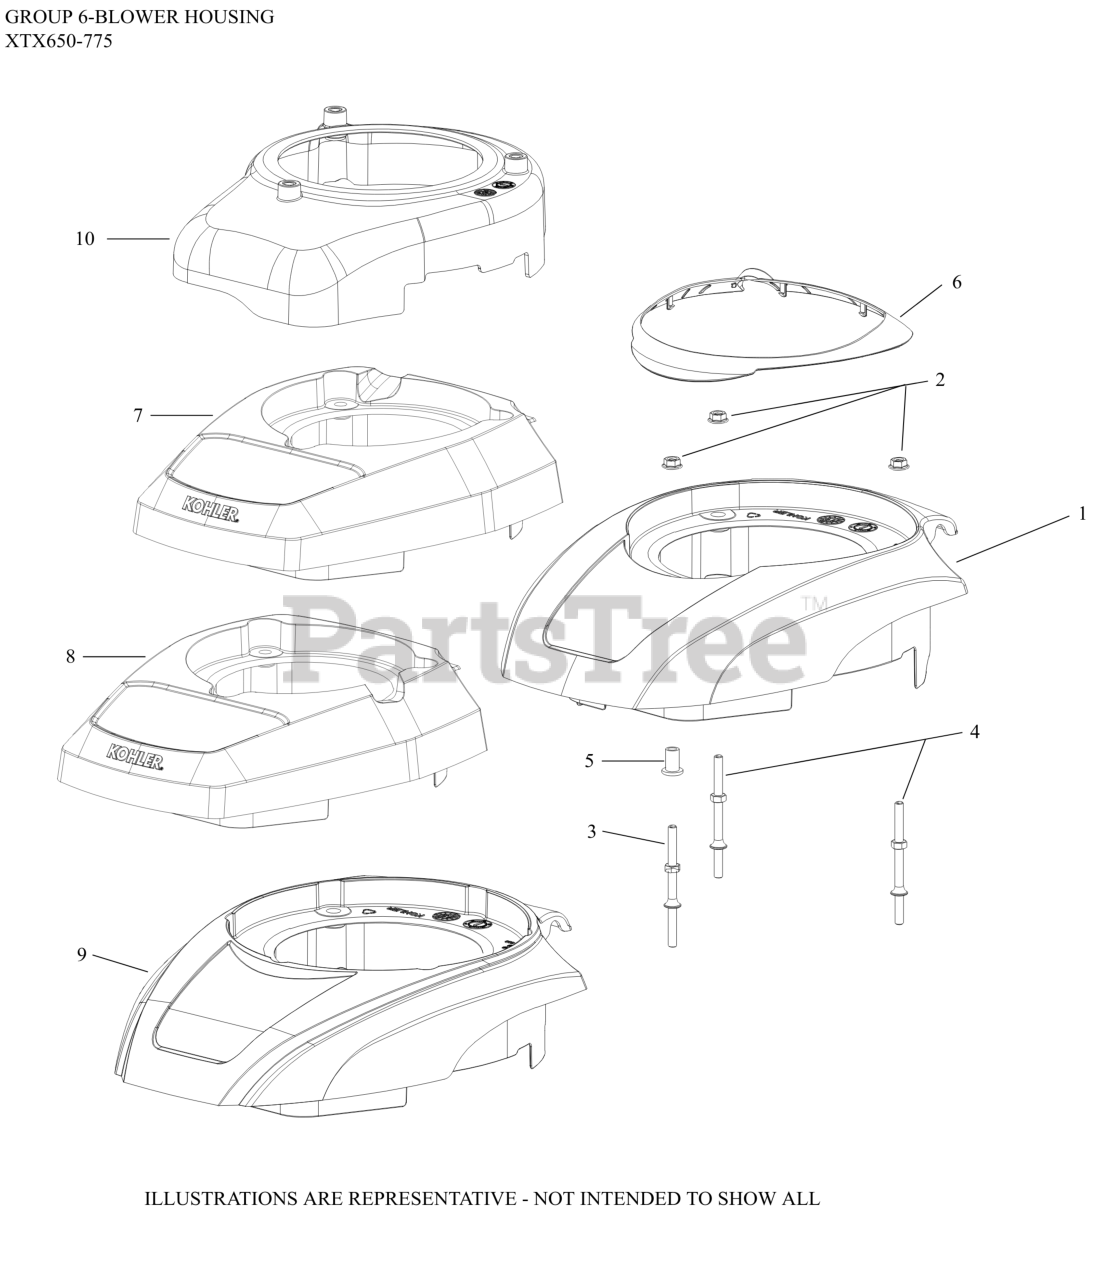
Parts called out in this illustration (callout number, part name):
1	COVER, ENGINE
2	NUT, HEX FLANGE (M6) - USE 14 100 16-S
3	STUD-USE 14 072 25-S
4	STUD-USE 14 072 26-S
